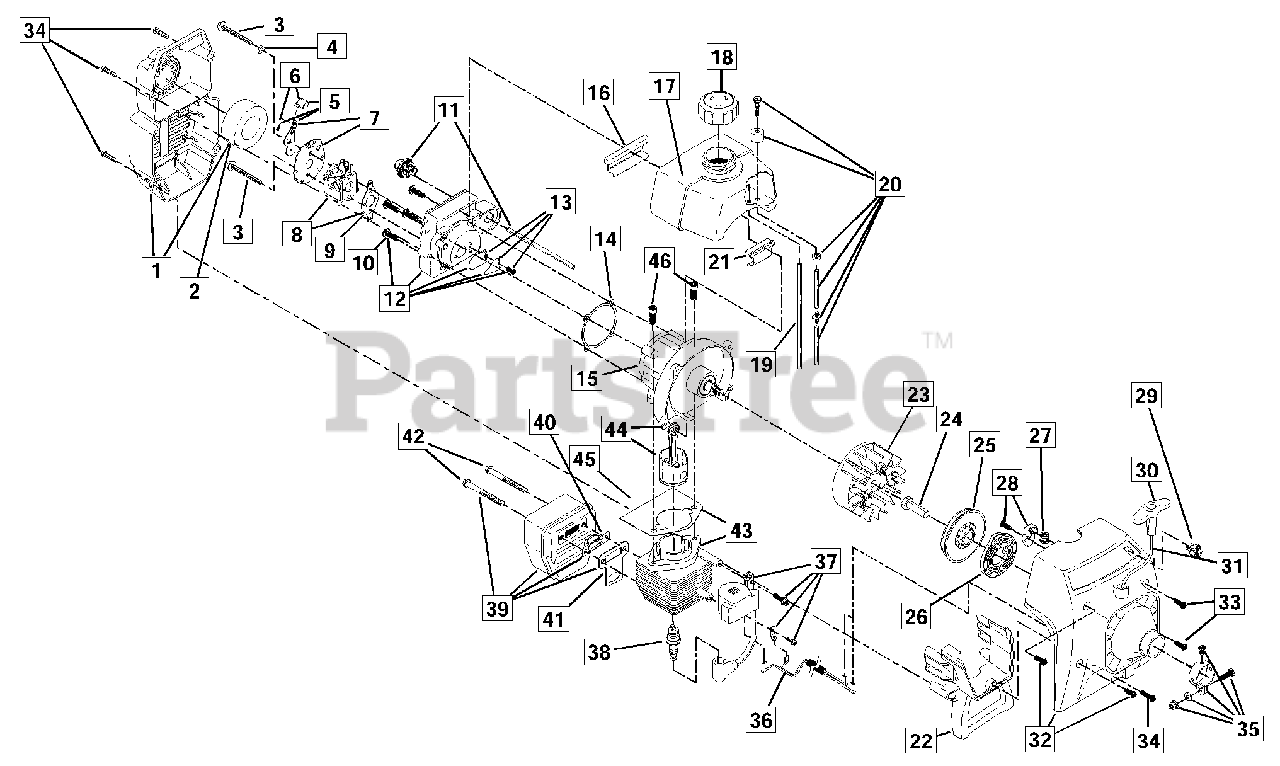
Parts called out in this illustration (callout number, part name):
1	Air Cleaner/Muffler Cover Assembly
2	Air Cleaner Filter
3	Carburetor Mounting Screws
4	Wavey Washer
5	Choke Lever Assembly
6	Choke Knob and Screw
7	Choke Lever and Plate
8	Carburetor Assembly
9	Carburetor Gasket
10	Carb Mount Screw
11	Primer and Hose Assembly
12	Carb Mount Assembly
13	Reed Assembly
14	Crank Case Gasket
15	Crank Case Service Assembly
16	Rear Mounting Pad
17	Fuel Tank Assembly
18	Fuel Cap Assembly
19	Fuel Return Line
20	Fuel Line Assembly
21	Front Mounting Pad
22	Shroud Extension and Stand
23	Flywheel Assembly
24	Square Nut Drive
25	Recoil Pulley Assembly
26	Recoil Spring
27	Rope Guide
28	Pulley Retainer Assembly
29	Switch Assembly
30	Pull Handle
32	Starter Housing Assembly
33	Housing Screw
35	Upper Clamp Assembly
36	Wire Lead
37	Module Assembly
38	Spark Plug
39	Muffler Assembly
40	Spark Arrestor
41	Exhaust Gasket
42	Muffler Mounting Bolt Assembly
43	Cylinder Assembly
44	Piston and Rod Assembly
45	Cylinder Gasket
46	Cylinder Bolt
